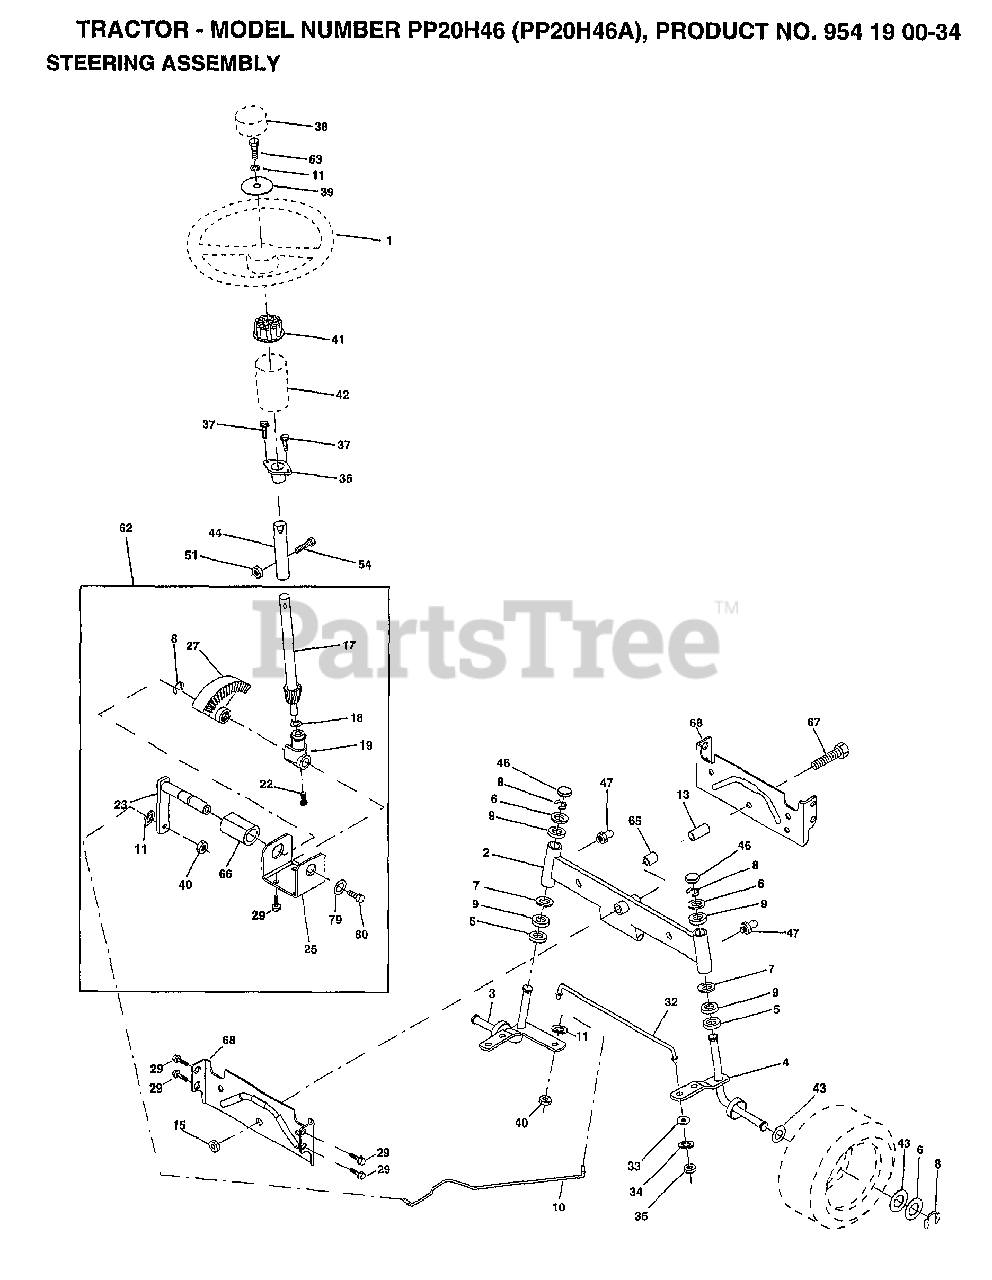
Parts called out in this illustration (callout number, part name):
2	AXLE ASM
3	SPINDLE.ASM.LH
4	"SPINDLE ASM,RH"
5	WASHER .T
6	WASHER
7	WASHER
8	RING
9	COL. SRTG. BEAR.
10	DRAGLINK-STAMPED
11	LOCKWASHER
13	BEARING AXLE
15	"NUT-LOC,FLANGE LT"
17	SHAFT ASM STEERIN
18	THRUST WASHER
19	SUPPORT.SHAFT.STEER
22	SCREW.HX.WSH.HD
23	SHAFT.ASM.PITMAN
25	BRKT-STEERING
27	GEAR SECTOR
29	SCREW
32	ROD.TIE.19.75
33	WASHER M
34	LOCKWASHER
35	NUT.LOCK.5/16-24
36	BUSHING.STEERING
37	"SCREW-TT,10-32 FL"
38	"INSERT,STR WHEEL"
39	WASHER T
40	GRIPCO NUT
41	ADAPTER LT
42	BOOT.STEER.PL
43	WASHER
44	EXT SHAFT STEERIN
46	CAP
47	ZERK M
51	NUT
54	BOLT
62	KIT.STEER.ASM
63	BOLT
65	SPACER AXLE
66	"BEARING-ARM,PITMA"
67	BOLT
68	BRACE AXLE
79	WASHER
80	BOLT.HX.NYLON3/8-16X3/
